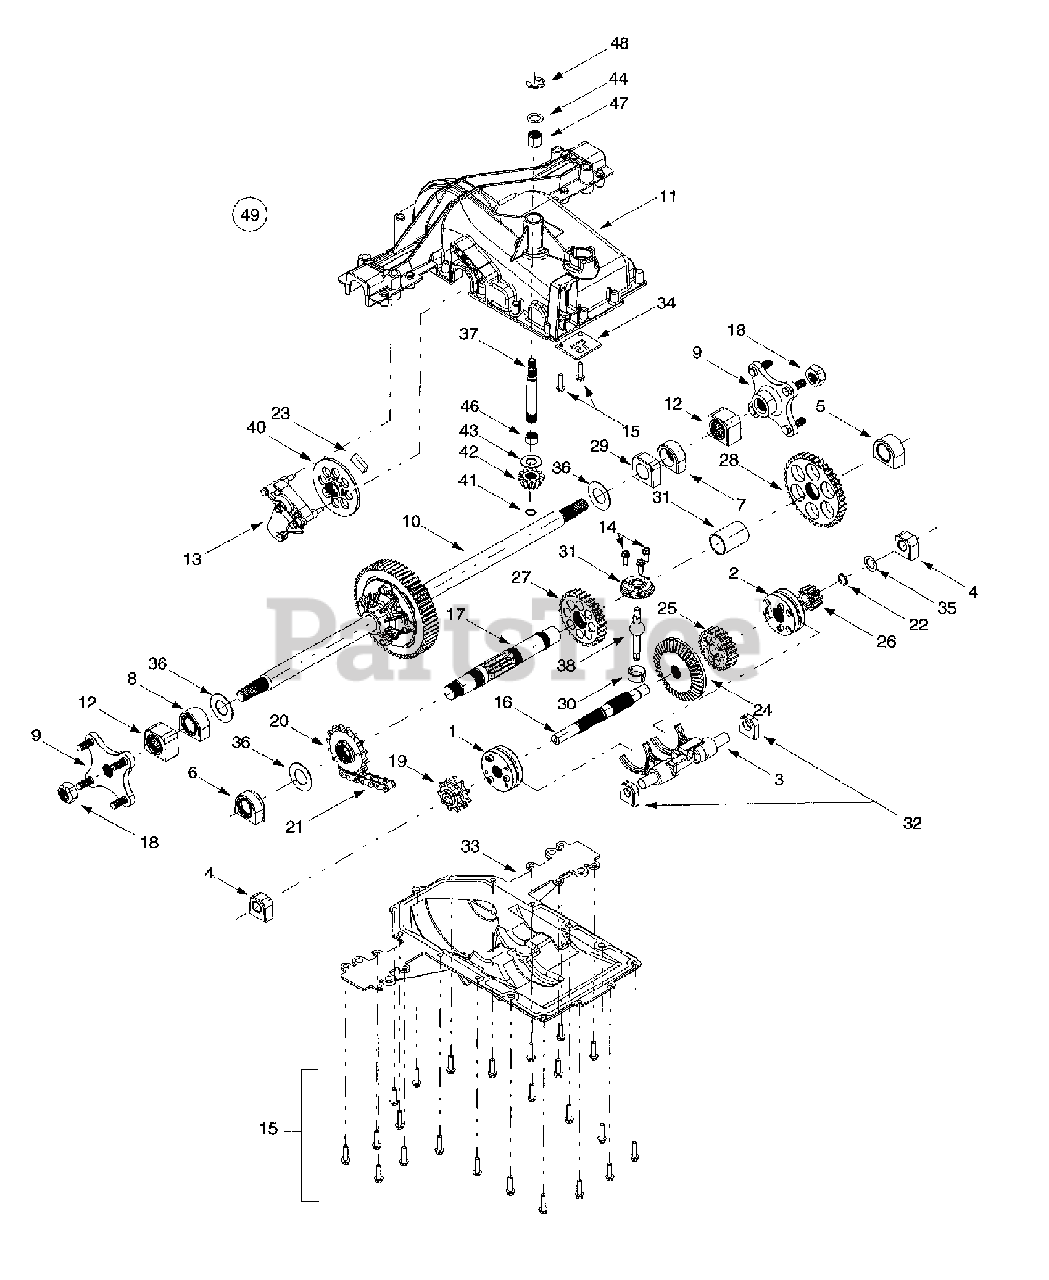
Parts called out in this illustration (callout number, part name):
1	Reverse Collar Assembly
2	Hi-Lo Collar Assembly
3	Shift Fork Assembly
4	Detent Block Assembly
5	Output Bearing Block Assembly
6	Output Seal Bearing Block Assembly
7	Inboard Sealed Axle Block Assembly
8	Inboard Sealed Axle Block Assembly
9	Wheel Hub Assembly
10	Differential Axle Assembly
11	Upper Housing
12	Axle Bearing Block Assembly
13	Brake Assembly
14	Self-tapping Screw, 1/4-20 x .75
15	Self-tapping Screw, 1/4-20 x 1.0
16	Drive Shaft
17	Output Shaft
18	Nut, 3/4-16
19	9-tooth Sprocket
20	16-tooth Sprocket
21	22-link Chain, .625
22	External Snap Ring
23	Brake Pad
24	41-tooth Bevel Gear
25	20-tooth Spur Gear
26	10-tooth Spur Gear
27	27-tooth Spur Gear
28	37-tooth Spur Gear
29	Inner Axle Bearing Block
30	Shifter Insert
31	Shifter Cover
32	Shifter Bearing Block
33	Lower Housing
34	Lockout Plate
35	Flat Washer, 5/8 x 1.0
36	Flat Washer, 1.01 x 1.86 x .060
37	Input Shaft
38	Shift Lever
40	Disc Brake
41	Retaining Ring, .56
42	13-tooth Bevel Gear
43	Flat Washer
44	Flat Washer, 5/8 x 1.0 x .040
46	Needle Bearing
47	Needle Bearing
48	E-ring, .75
49	Transmission Assembly Complete
